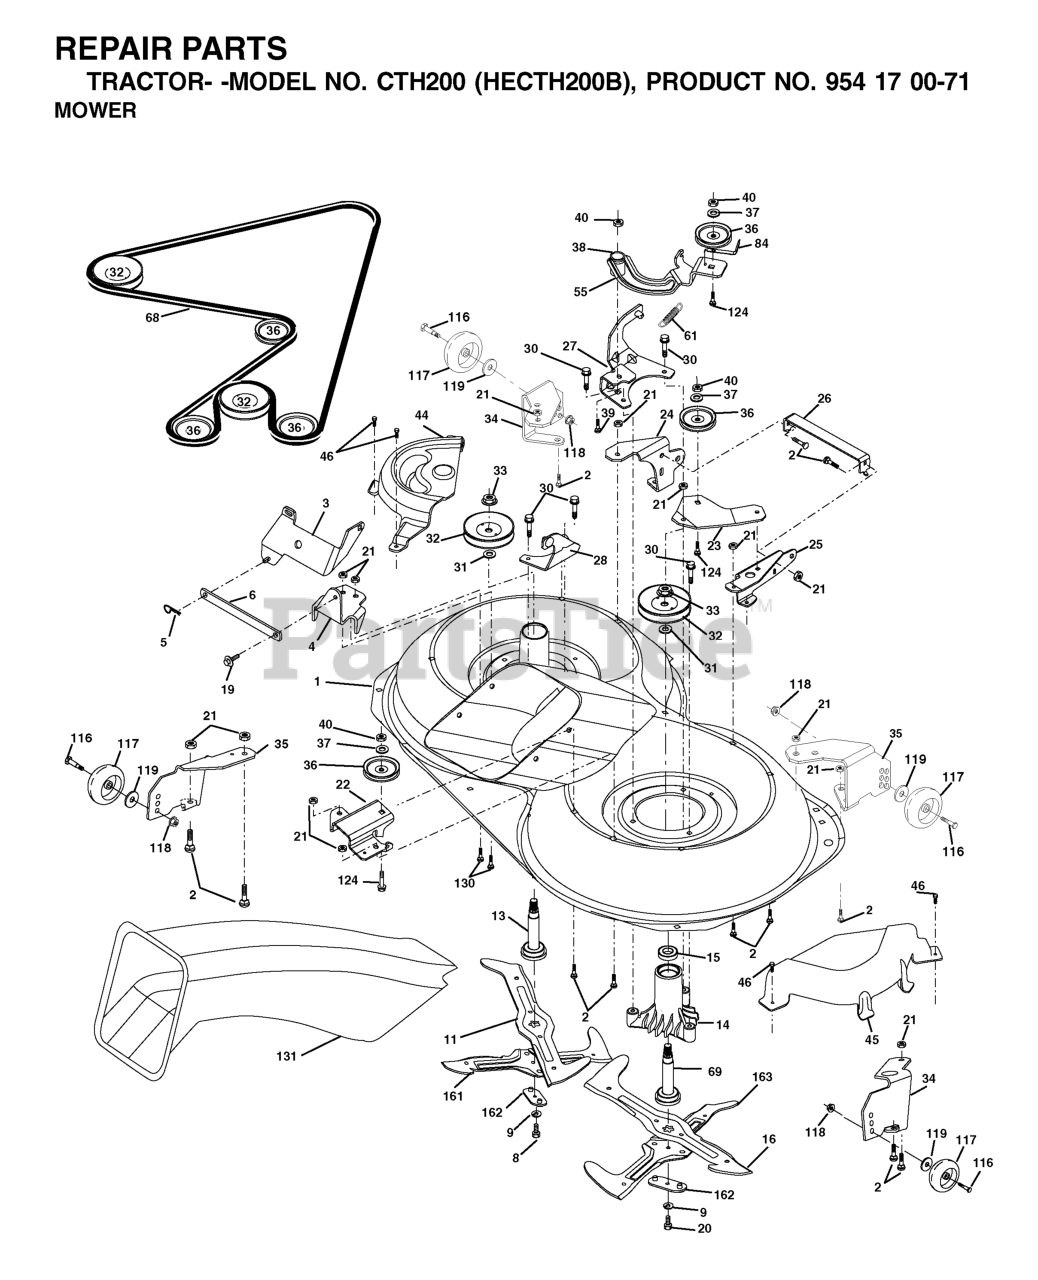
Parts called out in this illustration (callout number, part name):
1	Housing Asm. Mower 107 CRD
2	RP BOLT 5/16-18 X3/4 ZN/YEL GR
5	RETAINER SPRING
6	BAR.SWAY.92.CRD
8	BOLT.3/8-24X1.25 GR8
9	LOCKWASHER
11	BLADE.3N1.LH.CRD
13	SHAFT ASM VENT
14	HOUSING.MANDREL.VENTED (MACHD)
16	BLADE.3N1.RH.CRD
19	BOLT SHD 5/16-18
20	BOLT.3/8-24X1.25GR8. LHTHRD
21	LOCKNUT
22	BRACKET.IDLER.RR.107.CRD
25	BRACKET.SUSPENSION.RF.107.CRD
26	BRACE.SUPT.SUSP.FRT.CRD
28	BRACKET
30	SCREW, WASHER HEAD
31	WASHER
33	NUT, FLG TOPLOCK 9/16"
36	PULLEY.IDLER.4.25
37	WASHER
45	COVER.MANDREL.RH.CRD
46	SCREW.1/4-20X5/8
55	ARM.IDLER.107.CRD
68	HEX-BELT 107 MOWER
69	SHAFT.ASM.W/LWR.BRG.RH.THREAD
84	KEEPER, BELT IDLER
116	BOLT, SHOULDER
117	WHEEL GAGE DONUT
118	LOCKNUT
119	WASHER.5/16.FLAT.STE.STD.
124	BOLT.3/8-16X1.50
130	BOLT.CARR.SQNK.5/16-18UNC.X3/4
131	CHUTE BAGGER
163	BLADE.CROSS.RH.CRD.107
